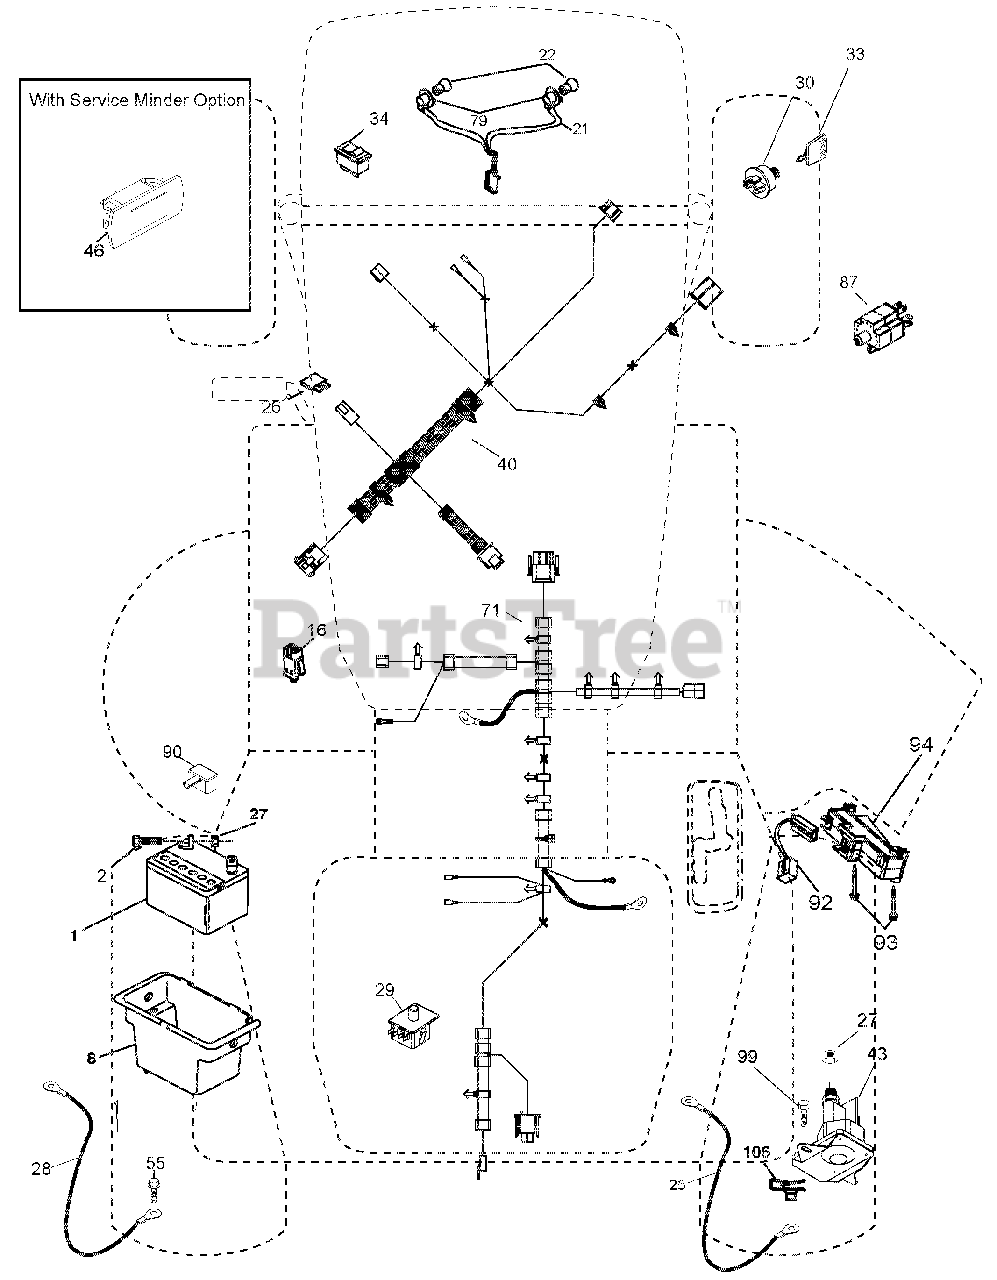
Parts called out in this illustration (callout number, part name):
1	BATTERY.12.VOLT.28.AMP.WET
2	BOLT.HEX.HD.1/4-20UNC X 3/4
8	BOX.BATTERY.MNT.REAR.LT.TEX.BL
16	SWITCH.INTERLOCK.NONO.GRAY
21	HARNESS ASM.LIGHT.22"(4152J)
22	BULB.LIGHT.#1156
25	CABLE STARTER 6 G4. BL/RED14.5
26	FUSE.20 AMP.
27	Nut, Keps Hex 1/4-20 unc
28	CABLE.BLACK.22"REAR BATT.TEX
29	SWITCH.SEAT.DELTA.OPC.9LB.
30	SWITCH.IGN.DLTA.P-IN.ROS
33	KEY/CHAIN.BLISTER PACK.GEN.USA
34	SWITCH.LIGHT/RESET.B/B/RED.
40	HARNESS IGN ELEC RELAY
43	SOLENOID.W/BRASS PLUNGER.2005
55	SCREW.5/16-18X3/4.SMGML.TAP/R
71	HARNESS.IGN.CHASSIS.TEX
79	SOCKET ASM.BULB.TWISTLOCK
87	SWITCH.INTRLCK.CLUTCH.CABLE.TX
90	COVER TERMINAL BATTERY FR. TEX
92	HARNESS.PIGTAIL.CONSLE.ROS.MLK
93	SCREW.PLASTITE.10-14 X 2.0
94	MODUAL REVERSE ROS
